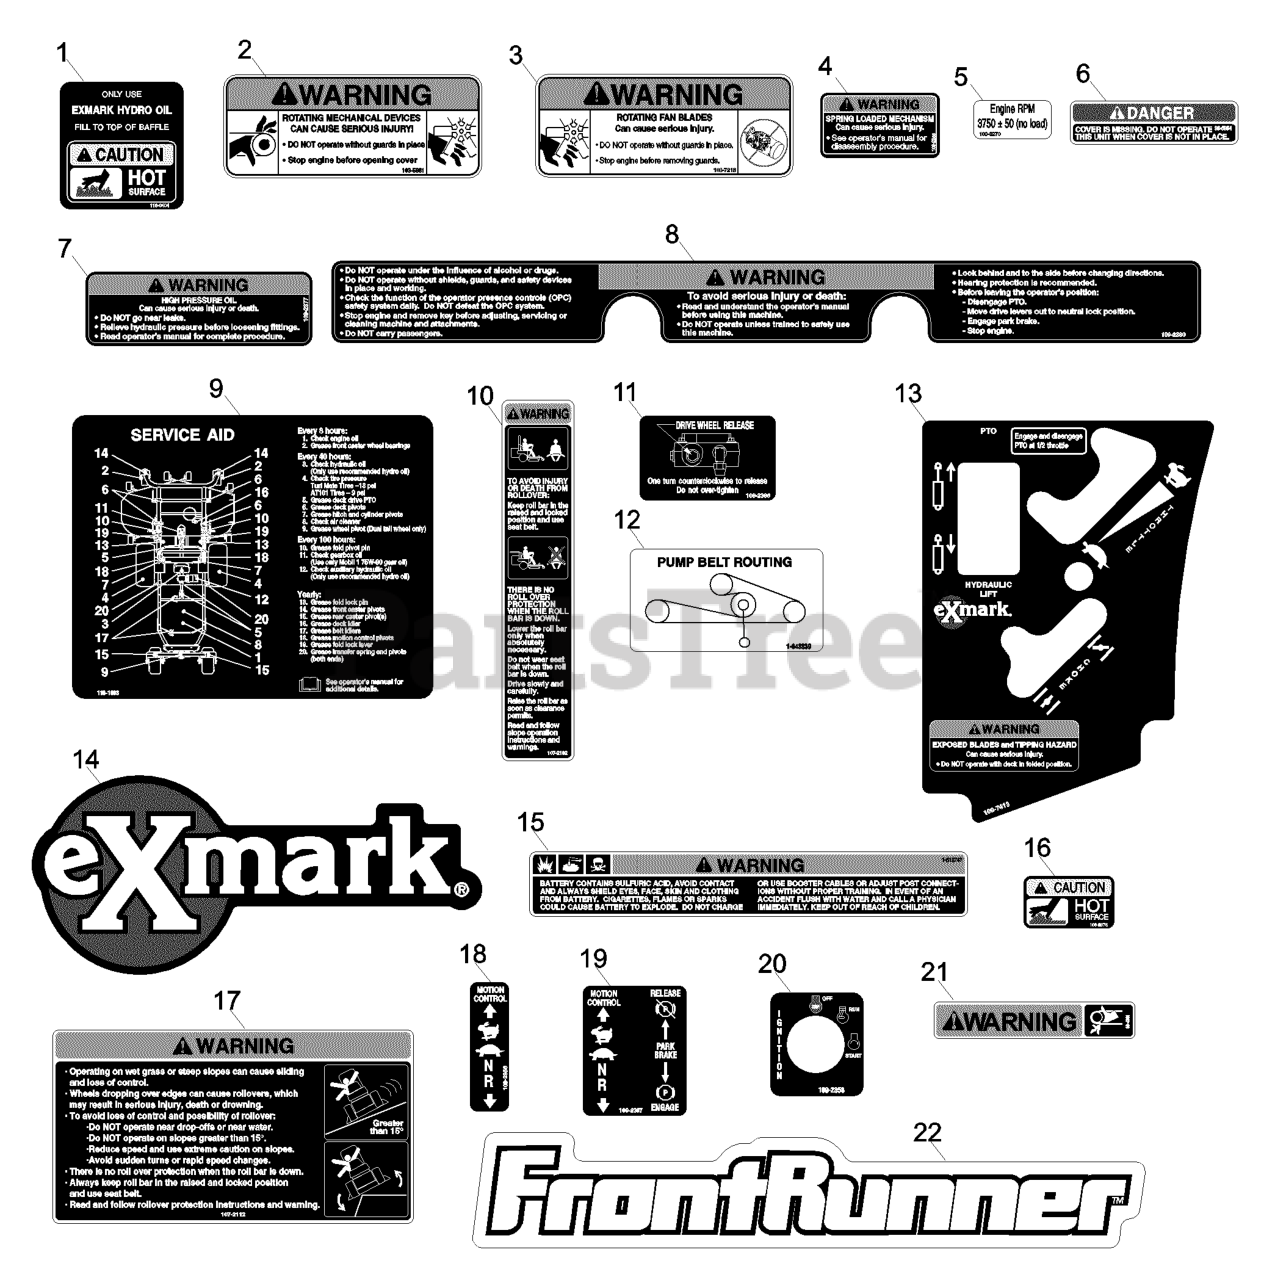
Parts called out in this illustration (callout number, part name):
1	DECAL-HYDRAULIC TANK
2	DECAL-DEVICES, ROTATING
3	DECAL,PUMP FAN WARNING
4	DECAL,SPRING LOADED
6	DECAL-COVER, MISSING
7	DECAL,HIGH PRESSURE OIL
8	DECAL,TOP CONSOLE
9	DECAL,FR SERVICE AID
10	DECAL-WARNING, FOLDING RO
11	DECAL,PUMP DRIVE RELEASE
12	DECAL-ROUTING, BELT
13	DECAL,CONTROL FMZ A/C
14	DECAL,EXMARK LOGO
15	DECAL-BATTERY
16	DECAL-CAUTION
17	DECAL-WARNING
18	DECAL-CONTROL, MOTION
19	DECAL,MOTION CNTL/PARK BR
20	DECAL,IGNITION
21	DECAL-WARNING
22	DECAL,FRONTRUNNER
